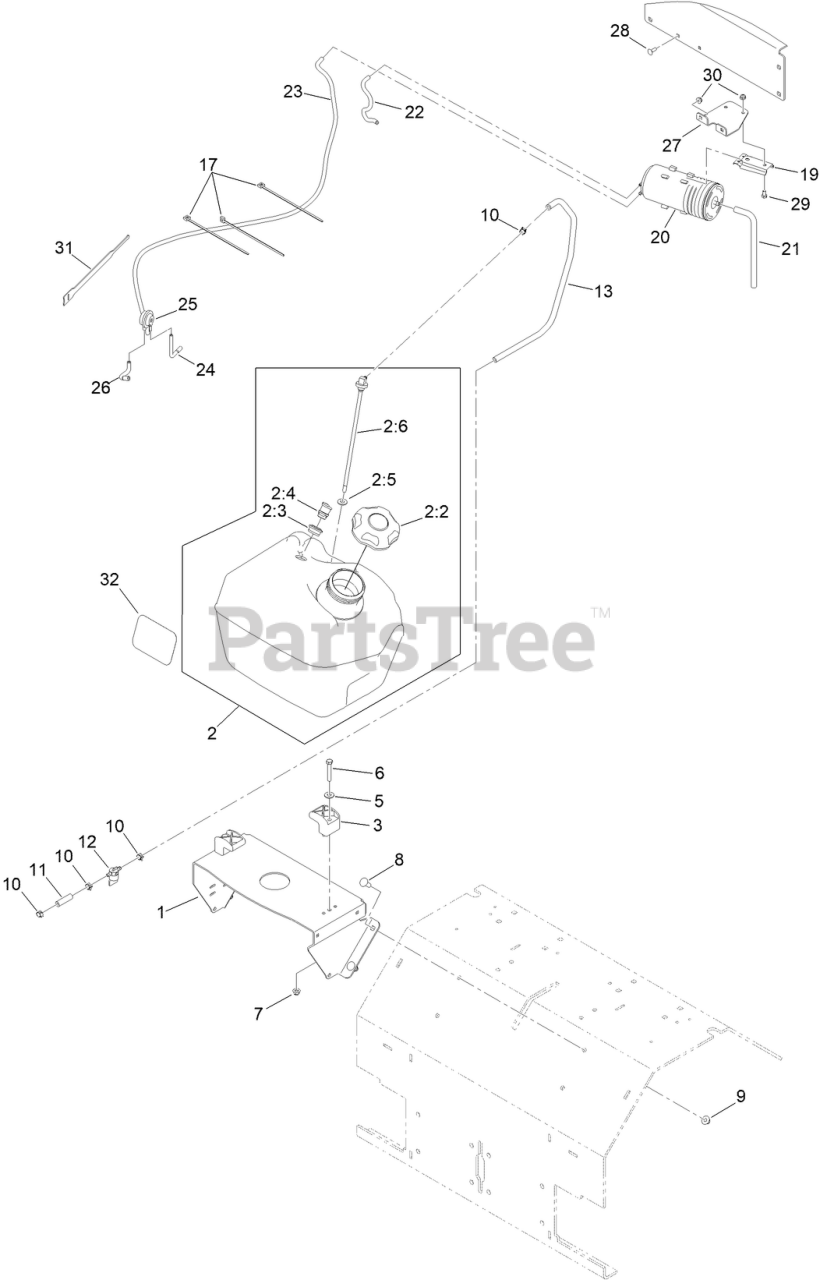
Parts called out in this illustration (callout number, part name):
1	SUPPORT-TANK, FUEL
2	ASM-FUEL TANK, 5 GAL, UNLABEL
2:2	CAP-FUEL, RATCHETING
2:3	GROMMET
2:4	VALVE-VENT, FUEL
2:5	BUSHING
3	CLAMP-TANK
5	WASHER-FLAT
6	SCREW-HH
7	NUT-HF, NI
8	SCREW-CARR
9	NUT-HF, NI
10	CLAMP-HOSE
11	HOSE-FUEL
12	VALVE-FUEL
13	HOSE-LINE, GAS
17	TIE-CABLE
19	BRACKET-CANISTER, CARBON
20	CANISTER-CARBON, 800CC
21	HOSE-VENT, CANISTER
22	HOSE-EMISSIONS
23	HOSE-VENT, FORMED
24	HOSE-VENT, FORMED
25	VALVE-CONTROL, VACUUM
26	HOSE-VENT, FORMED
27	BRACKET-MOUNTING, CANISTER
28	BOLT-CARR
29	SCREW-HH
30	NUT-HF
31	STRAP-VELCRO, CABLE TIE
32	DECAL
